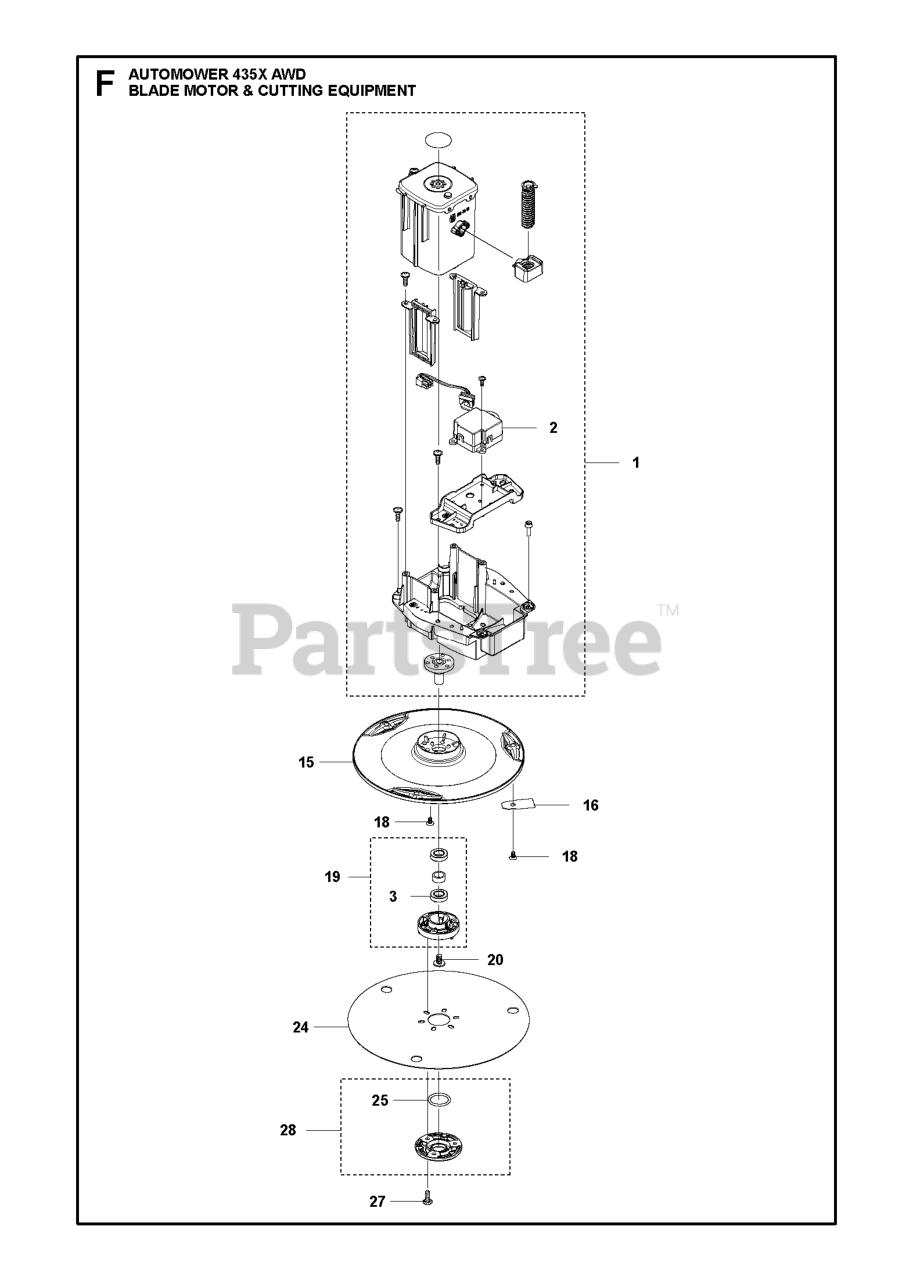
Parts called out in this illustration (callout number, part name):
3	BALL BEARING 2 RS,TIGHT CLEAR
3	BALL BEARING BALL BEARING 535
15	GUARDS
16	HUS BLADE SET 300 PCS
16	HUS BLADE SET 9 PCS
16	HUS BLADE SET 45 PCS
18	SCREW HEXAGON SOCKET BUTTON HE
19	BEARING HOUSING ASSY
25	O-RING 20X2,5 MM
27	SCREW 14MM
28	COVER KIT BEARING
